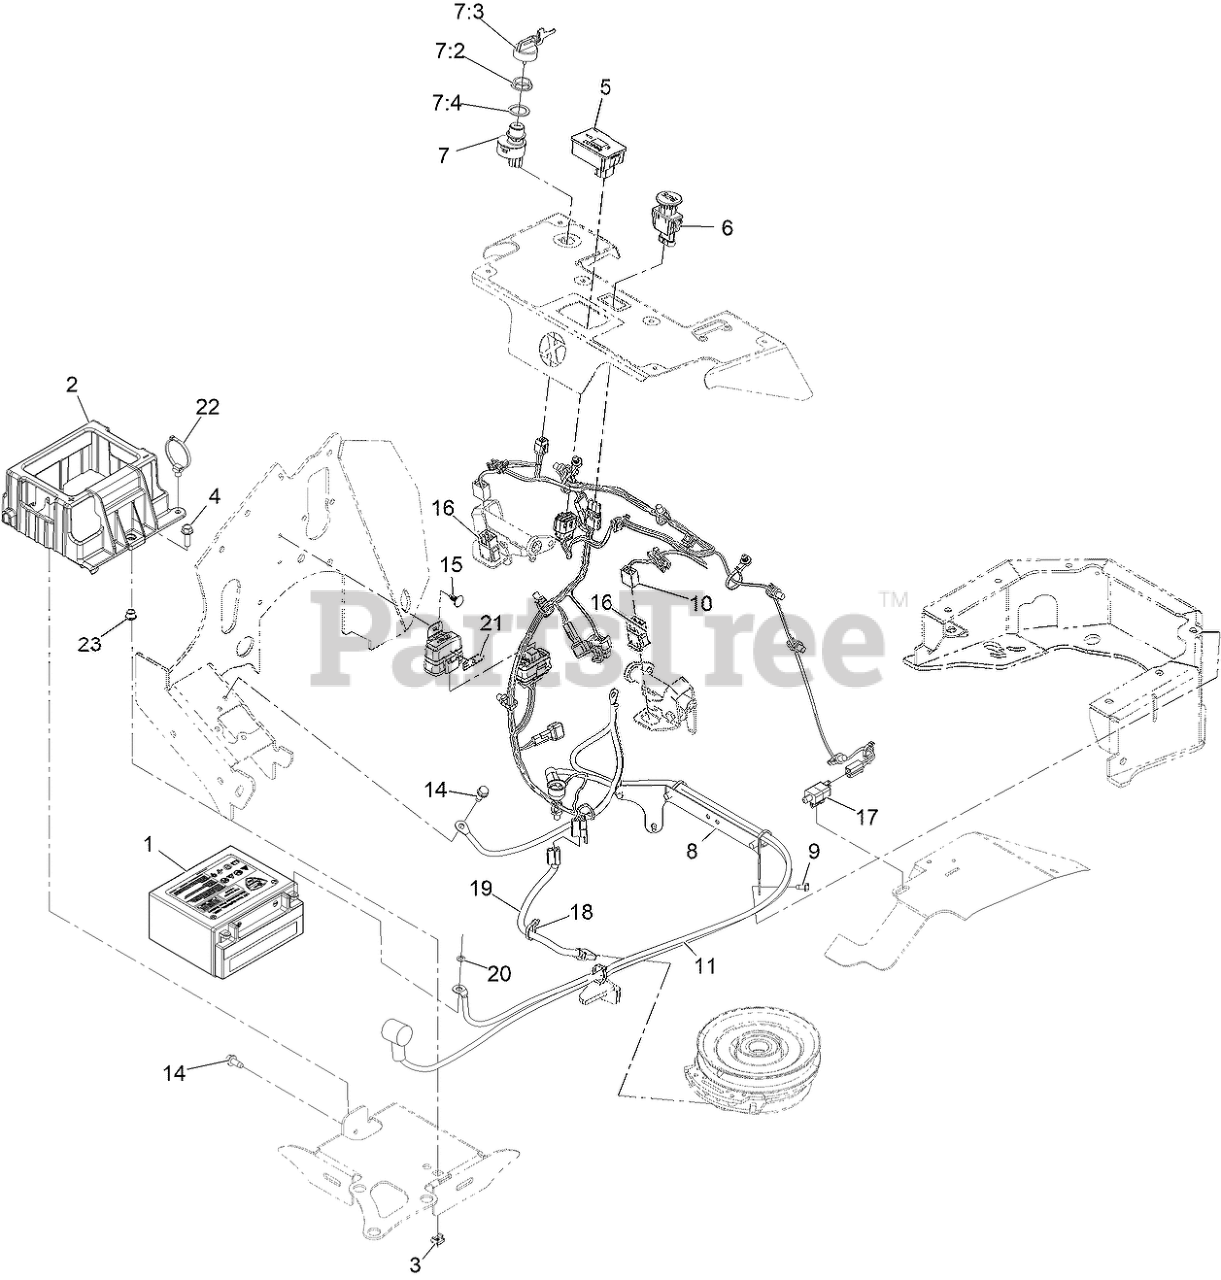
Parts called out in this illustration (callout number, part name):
1	BATTERY, AGM, NON-SPILLABLE
2	BOX, BATTERY
3	NUT, SNAP
4	Screw-HHF
5	Module-Hour Meter
6	SWITCH-PTO, SEALED
7	IGNITION SWITCH ASM
7:2	NUT-MOUNTING
7:3	IGNITION KEY SET
7:4	WASHER-BACKUP
8	SUPPORT, BATTERY CABLE
9	SCREW-HWH
10	HARNESS-WIRE
11	HARNESS-BATTERY
14	SCREW-THD ROLL, HWH
15	PLUG-PLASTIC
16	SWITCH-DELTA
18	TIE-CABLE
19	HARNESS-CLUTCH
20	WASHER-SPRING
21	DECAL-FUSE
22	CLIP-TIE
23	Bushing-Flange
